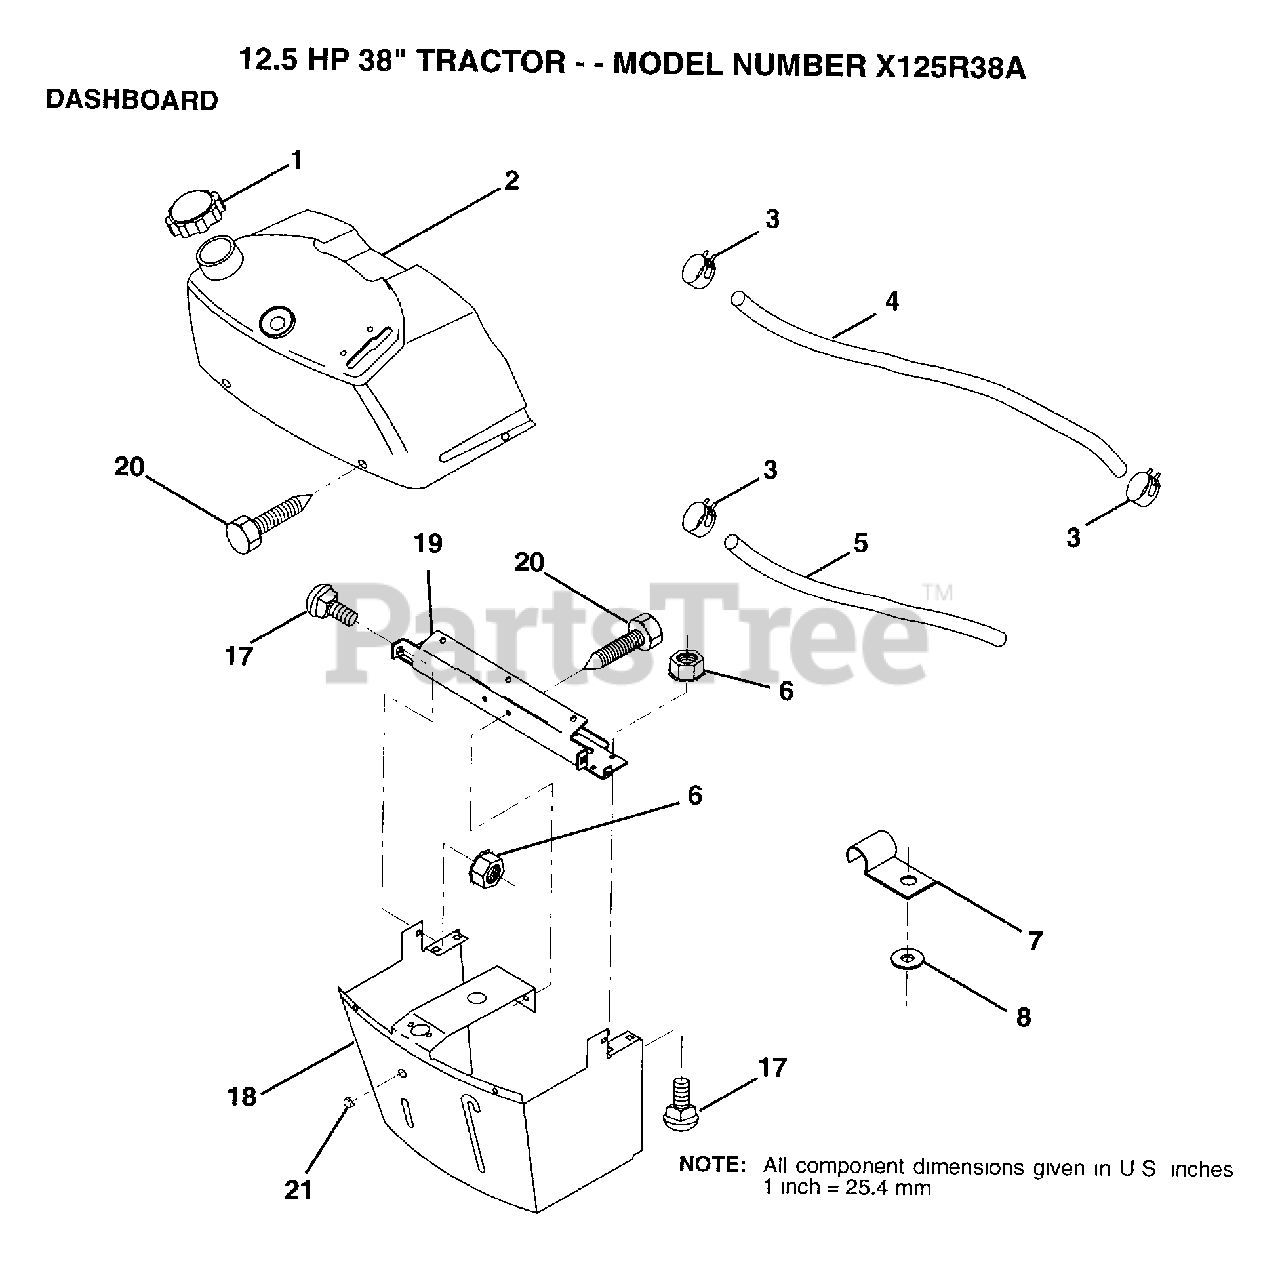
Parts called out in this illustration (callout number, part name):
1	CAP.FUEL.N/VENT
2	TANK.ASM.DASH.LR
3	HOSE CLAMP
5	FUEL LINE T
6	NUT
7	CLIP T
8	WASHER PM
17	BOLT
18	SUPT ASM DASH
19	CROSS BRACE
20	SCREW.1/4-20X1/2
21	PLUG DOME
